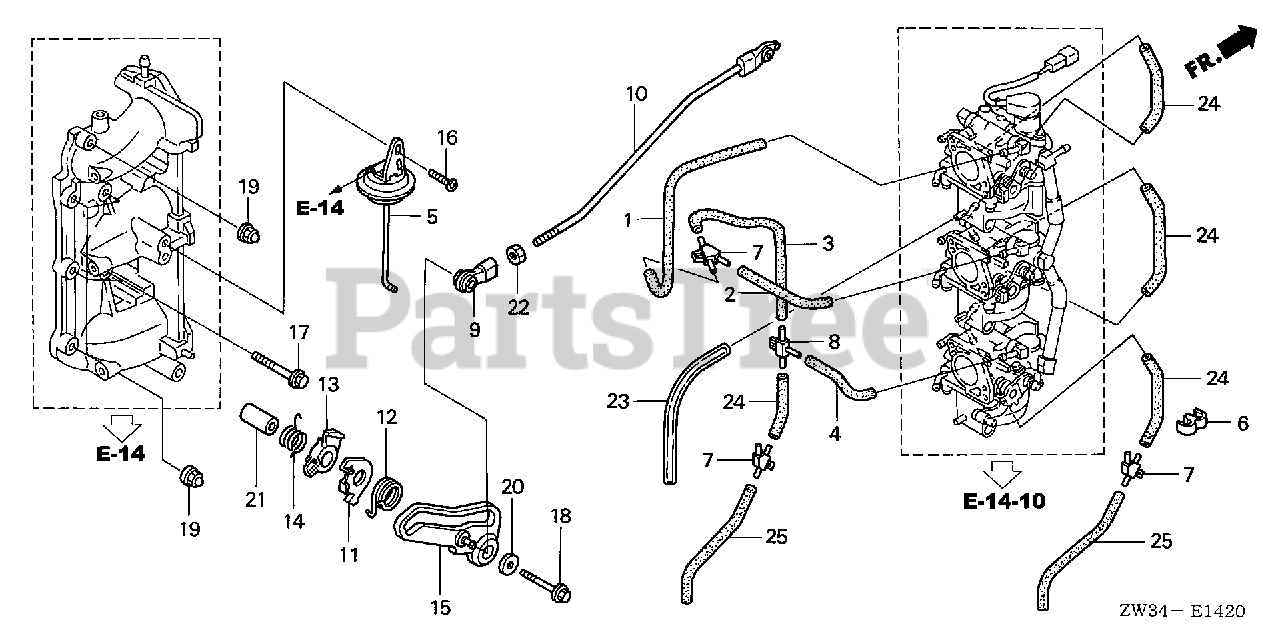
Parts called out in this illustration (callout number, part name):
1	TUBE A, AIR VENT
2	TUBE B, AIR VENT
3	TUBE C, AIR VENT
4	TUBE D, AIR VENT
5	DIAPHRAGM ASSY.
6	CLAMP, TUBE (7.5X2)
7	JOINT, THREE WAY
8	JOINT, THREE WAY
9	LINKAGE, PIVOT
10	ROD, THROTTLE
11	PLATE, ASSIST
12	SPRING, ASSIST
13	CAM, THROTTLE OPENER
14	SPRING, OPENER CAM RETURN
15	CAM, THROTTLE
16	BOLT, TORX (6X14)
17	BOLT, FLANGE (6X32)
18	BOLT, FLANGE (6X40)
19	NUT, CAP (6MM)
20	WASHER, PLAIN (6MM)
21	COLLAR (6.7X12.5X24)
22	NUT, HEX. (5MM)
23	BULK HOSE, VINYL (4.5X8X1000) (4.5X8X750)
24	BULK HOSE, VACUUM (4.5X1000) (4.5X135)
25	BULK HOSE, VACUUM (4.5X1000) (4.5X135)
